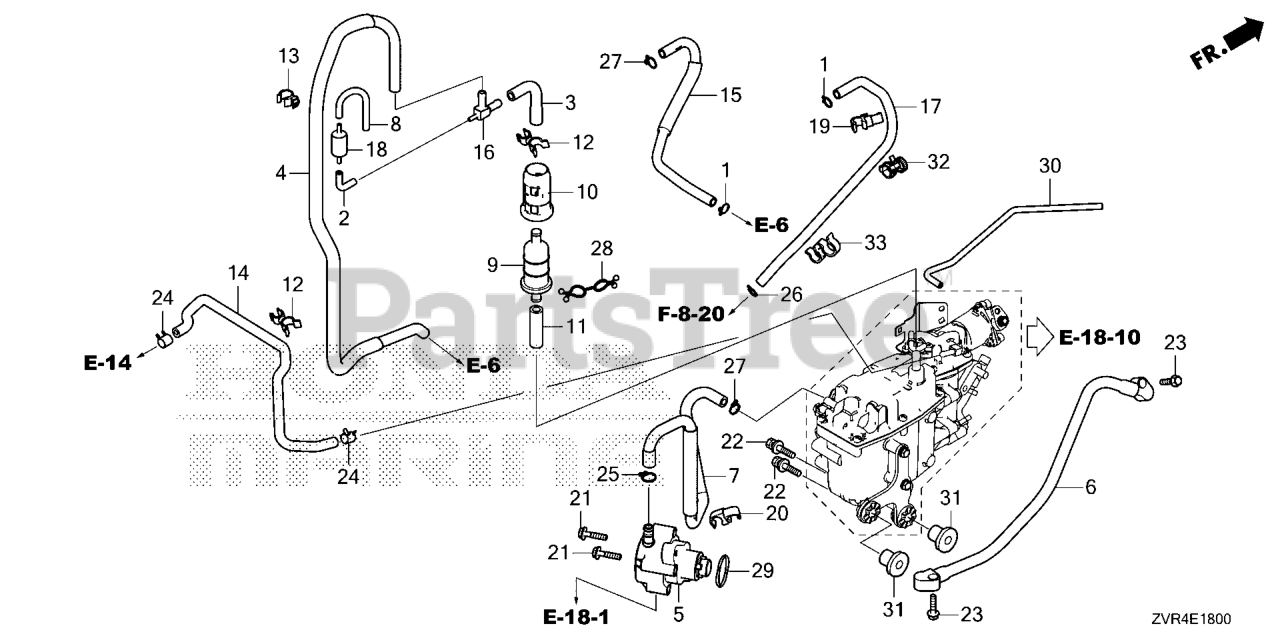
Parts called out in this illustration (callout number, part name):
1	CLIP, TUBE (ENGINE NO.)
2	TUBE C, AIR VENT
3	TUBE B, AIR VENT
4	TUBE, AIR VENT
5	PUMP ASSY., FUEL (MSDS)
6	HOSE, FUEL
7	TUBE B, FUEL
8	TUBE D, FUEL
9	FILTER, FUEL PUMP
10	SUSPENSION, STRAINER
11	TUBE B, FUEL
12	CLAMP, HOSE
13	CLAMP, PIPE
14	HOSE, PRESSURE REGULATOR RETURN
15	TUBE COMP F, WATER
17	TUBE COMP G, WATER
18	VALVE, CHECK
19	CLIP, R. BRAKE WIRE
20	CLIP, SENSOR HOSE
21	BOLT, FLANGE (6X27)
22	BOLT-WASHER (8X35)
23	BOLT, FLANGE (6X25)
24	CLAMP, TUBE (D10.7)
25	CLIP, TUBE (B1 14.5)
26	CLIP, TUBE (B1 11)
27	CLIP, TUBE (B12)
28	CLIP, FUEL HOSE
29	O-RING (33.2X2.4) (NOK)
30	TUBE, DRAIN
31	COLLAR (8.5X14.5)
32	CLIP, TUBE (135MM) (BLACK)
33	CLAMP, PURGE HOSE (NOT AVAILABLE)
